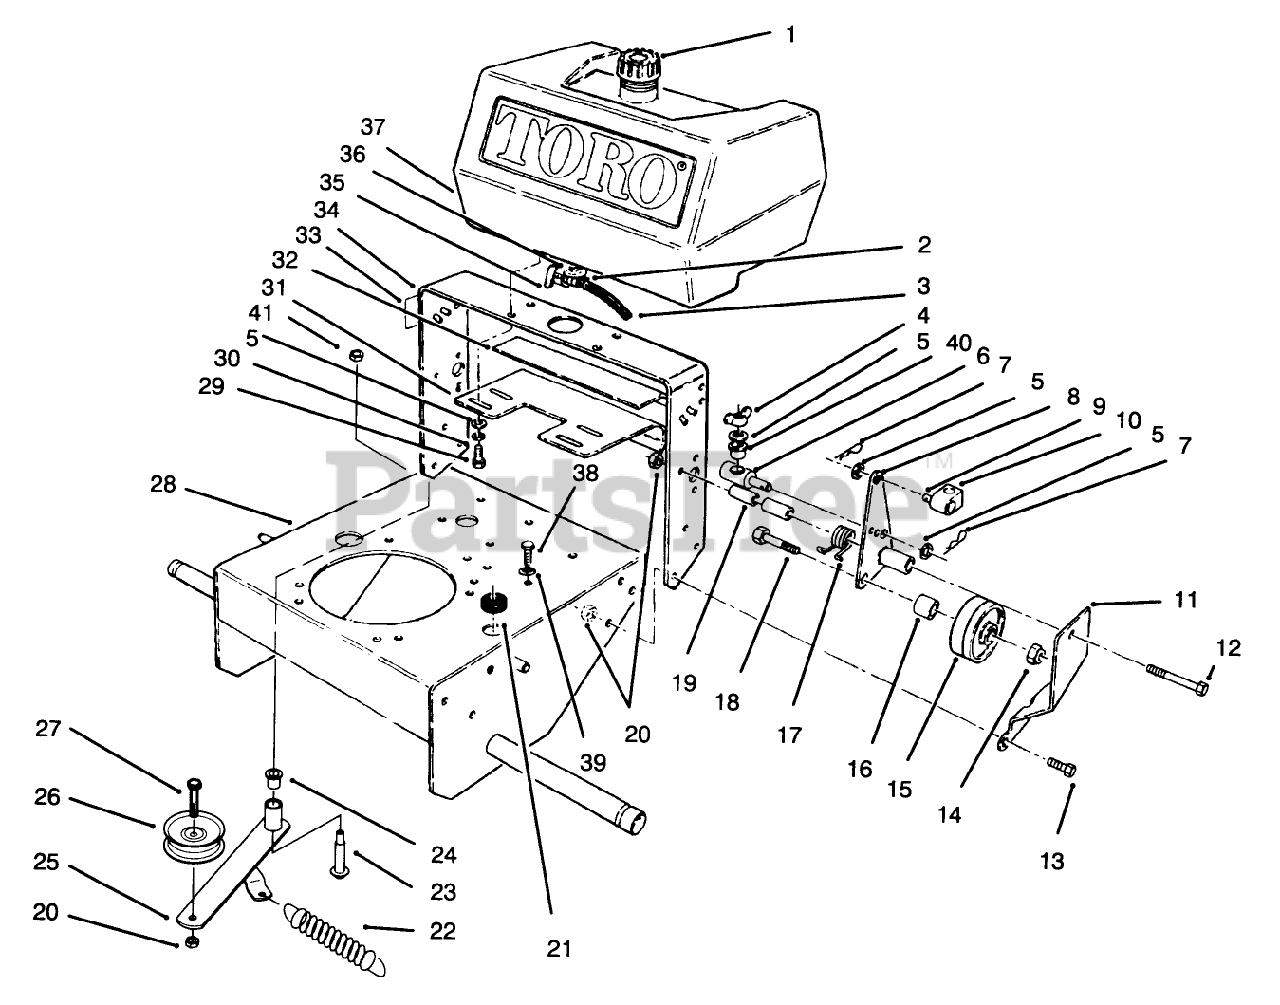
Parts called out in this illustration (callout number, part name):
1	GAS CAP ASM
3	HOSE-FUEL
4	NUT-WING
5	WASHER-PLAIN
6	FITTING-ROD
7	PIN-COTTER
8	BRACKET-Idler, LH
9	PIN-CLEVIS
10	FITTING-ROD
11	Bracket-LH
12	SCREW-HH
13	SCREW-HH
14	NUT-LOCK, NI
15	IdlerWheel
16	WHEEL IDLER SPACER
17	SPRING-TORSION, LH
18	SCREW-LEVELER
19	SPACER-PIVOT, IDLER
20	NUT-LOCK, NI
21	GROMMET
22	SPRING
23	BOLT-WHEEL
24	BUSHING-FLANGE
25	Lever-Idler (Incl. Ref. #24)
26	PULLEY
27	SCREW-HH
28	Frame
29	SCREW-HH
30	WASHER-LOCK
31	Plate
32	DECAL-GROUND SPEED
33	DECAL-FUEL SHUT OFF
34	Frame Rear
35	VALVE-FUEL
36	O-RING
37	FUEL TANK
38	SCREW
39	WASHER-LOCK/EXT
40	BUSHING-NYLON
41	NUT-LOCK
